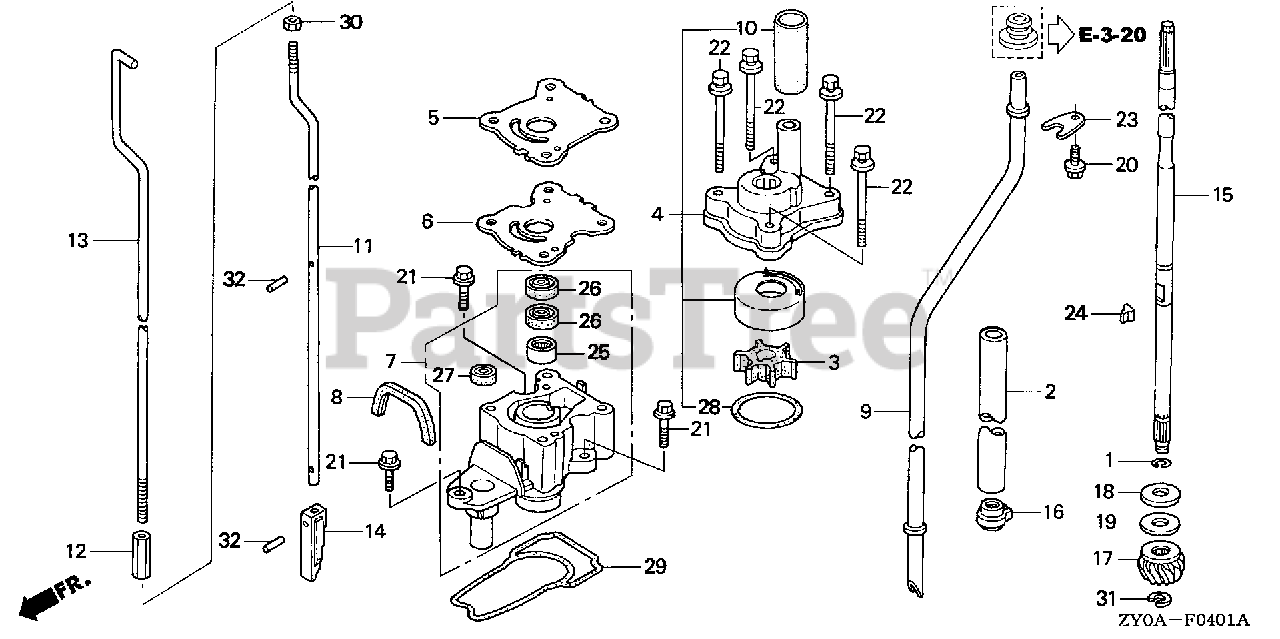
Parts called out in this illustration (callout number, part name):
1	CLIP, VALVE GUIDE
2	GUIDE, OIL (UL)
3	IMPELLER, PUMP (UL)
4	HOUSING ASSY., IMPELLER
5	COVER, IMPELLER
6	COVER, IMPELLER
7	HOUSING, WATER PUMP (UL)
8	GROMMET, WATER PUMP HOUSING
9	TUBE, WATER (UL)
10	RING, WATER TUBE SEAL
11	ROD B, SHIFT (UL)
12	JOINT, SHIFT ROD
13	ROD A, SHIFT (L)
14	ROD, PUSH
15	SHAFT, VERTICAL (UL)
16	SLINGER, OIL (UL)
17	GEAR, PINION
18	WASHER A, THRUST BEARING
19	WASHER B, THRUST BEARING
19	WASHER C, THRUST BEARING
20	BOLT, FLANGE (6X12)
21	BOLT, FLANGE (6X20)
22	BOLT-WASHER (6X90)
23	PLATE, WATER TUBE SETTING
24	KEY, WOODRUFF
25	BEARING, NEEDLE (15X21X12)
26	SEAL, WATER (15X24X5)
27	SEAL, WATER (6MM)
28	O-RING (42.2X2.4)
29	O-RING, WATER PUMP HOUSING
30	NUT, HEX. (6MM)
31	E-RING (8MM)
32	ROLLER (2.5X11.8)
